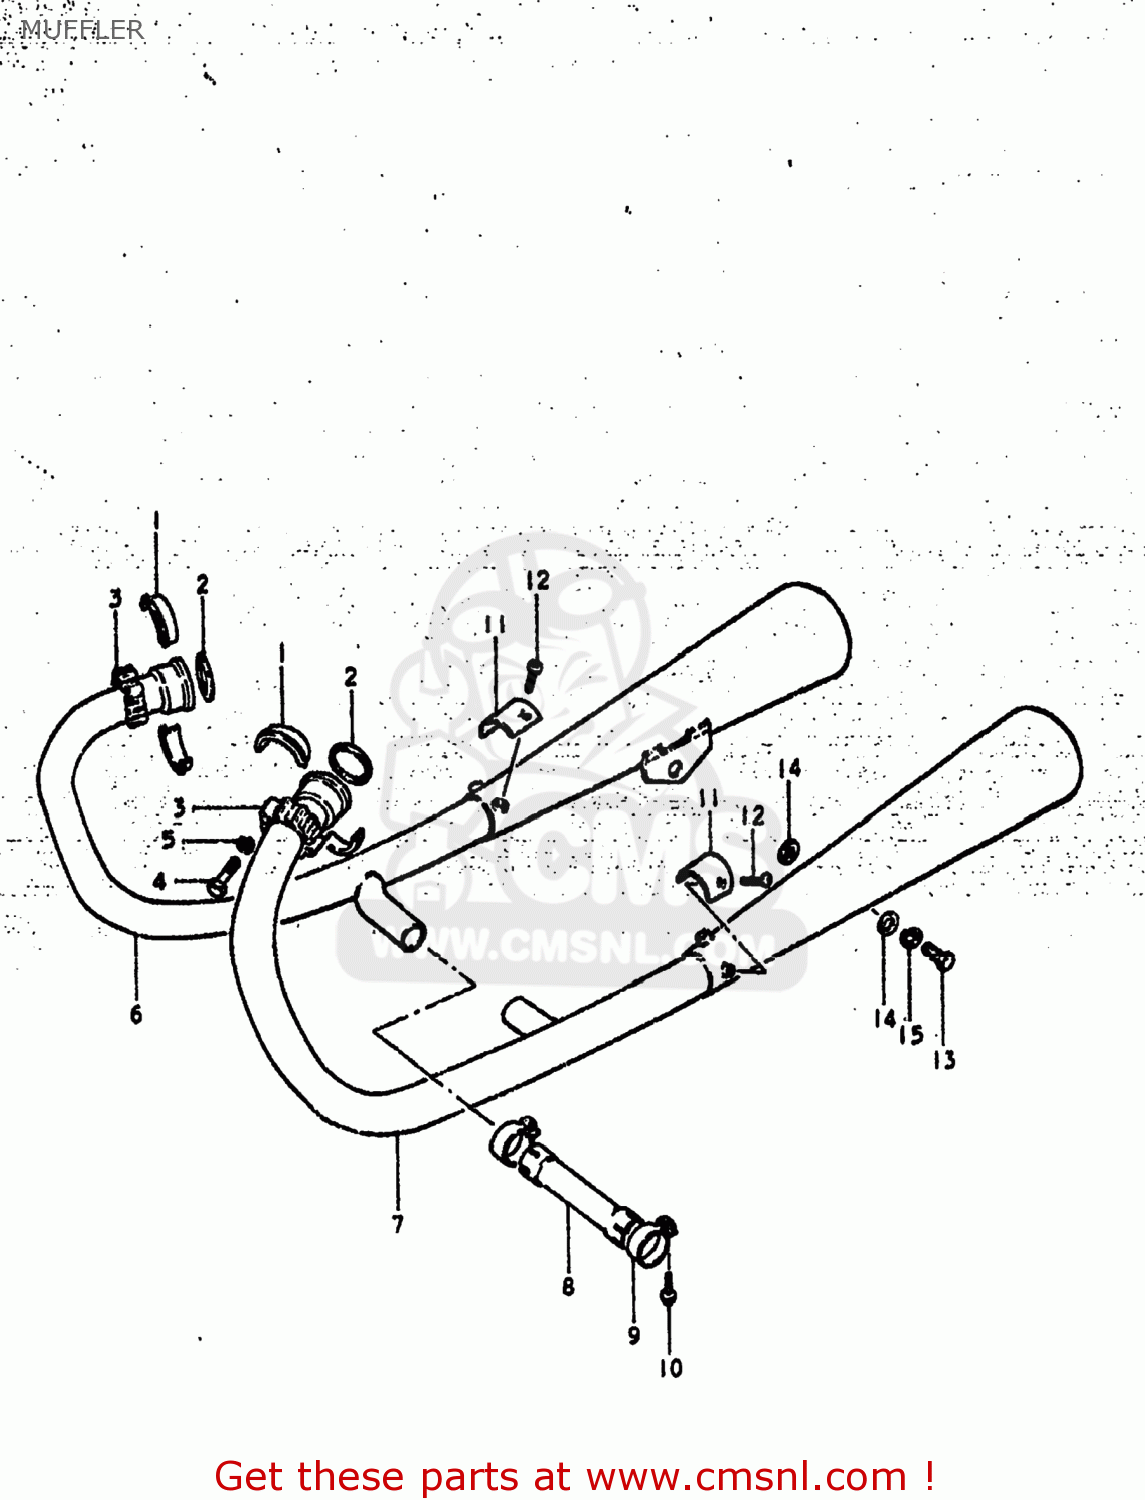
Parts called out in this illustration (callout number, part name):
1	PLATE,EXHAUST
2	GASKET,EXHAUST PIPE (NAS)
3	CLAMP,EXHAUST PIPE
4	BOLT
5	LOCK WASHER
6	BODY,MUFFLER
7	BODY,MUFFLER
8	PIPE,EXHAUST COUPLER
9	CLAMP
10	BOLT
11	COVER,MUFFLER
12	SCREW
13	BOLT 10X25
14	WASHER
15	LOCK WASHER
